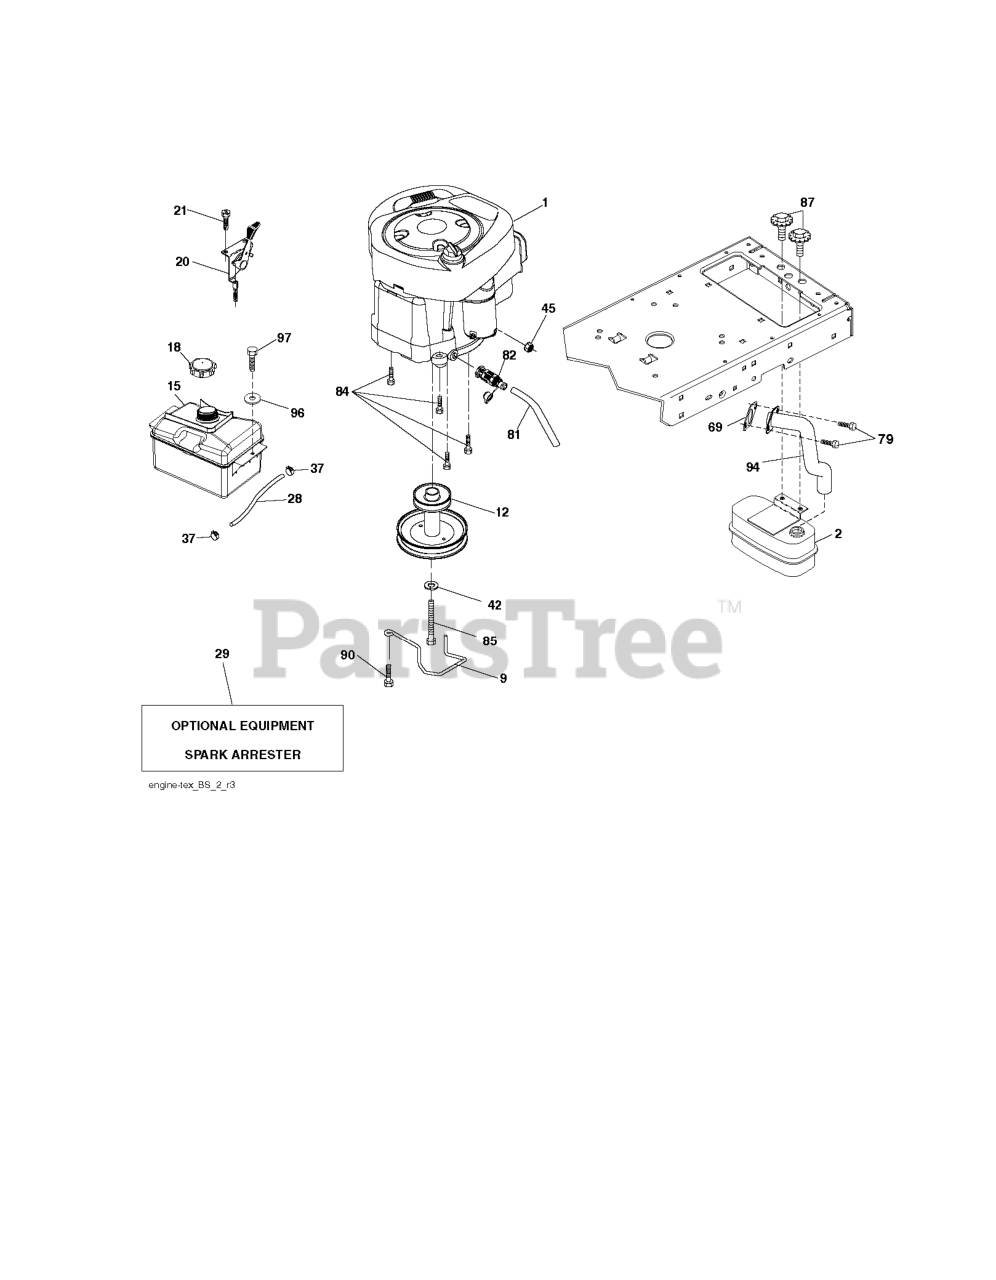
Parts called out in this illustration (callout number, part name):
2	MUFFLER.SINGLE.CYL.KOHL/B&S
9	KEEPER.BELT.ENGINE.4.2
12	PULLY ENGINE
15	TANK.ASM.FUEL.FR.2.5GA.
18	CAP ASM.FUEL.2.25"FR.
20	CONTROL.TH/CK.COBRA.KO
21	SCREW.#10 X 0.750.BOS
28	LINE.FUEL.20"FRONT.EMI
29	KIT.SPARK ARRESTOR 794945 B&S
37	HOSE CLAMP
42	LOCKWASHER
45	NUT
69	REPL BY 532 27 22-93
79	SCREW.SOCKET HD.5/16-1
81	TUBE, DRAIN OIL ASM.
82	VALUE.OIL.DRAIN
84	SCREW.3/8-16
85	BOLT HEX 7/16-20X4-1/4"
87	BOLT.5/16-18UNCX3/4 W/SEMS.BLK
90	SCREW 3/8-16X1
94	EXHAUST.TUBE.B&S.
97	SCREW HEXWSHR 1/4-20X3/4
